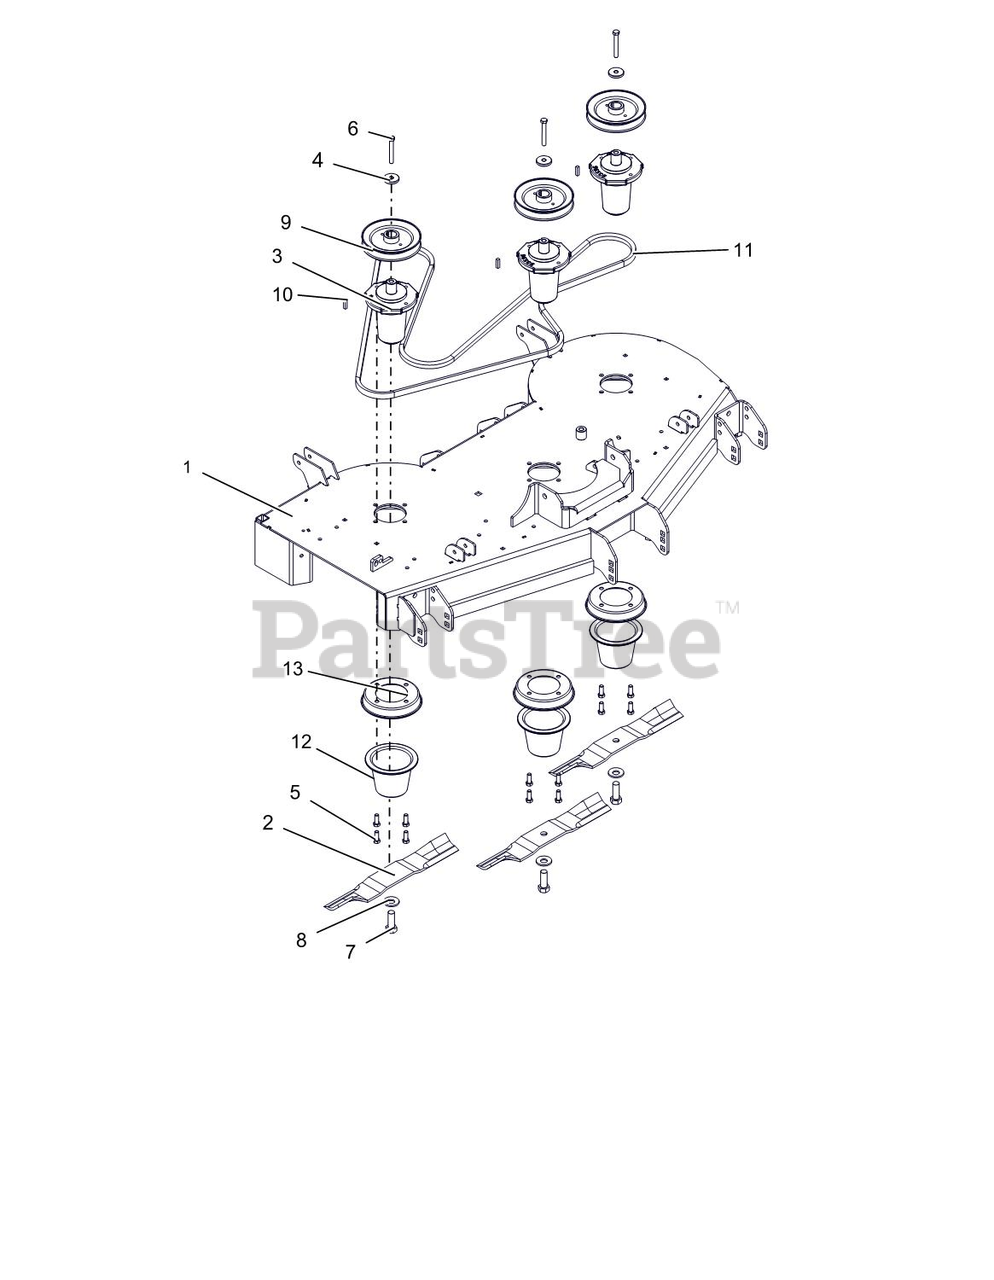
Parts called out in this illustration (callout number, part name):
1	KIT, 48" MOWER DECK W DECALS
2	BLADE, 16.19" MOWER (HI-LIFT)
3	ASM, MAINT FREE SPINDLE
4	RETAINER, SHEAVE
5	BLT-HEX .38-16X1.0 GR8 YZ EP30
6	BLT-HEX .38-16X2.75 GR8 YWZC
7	BLT-HEX .62-18X1.75 GR8 YWZC
8	WSHR-BLVL .669X1.535X.138
9	PULLEY, 1.00 ID X 5.75 OD
10	KEY, SQ .25X.25X1.00 RC 40-50
11	BELT, B-SECTI0N EPDM RAW EDGE
12	GUARD, SPINDLE LOWER
13	GUARD, SPINDLE TOP
